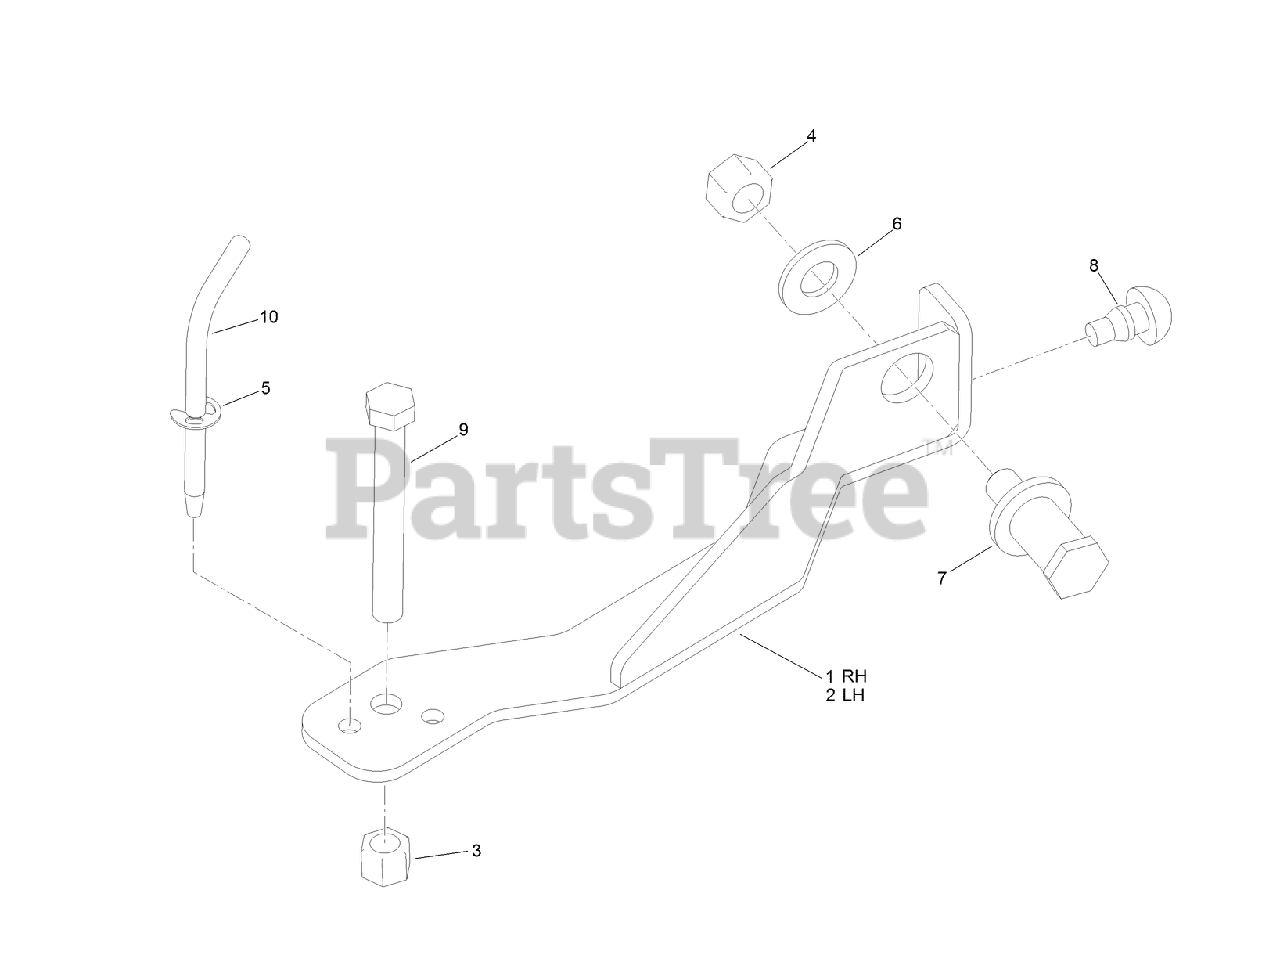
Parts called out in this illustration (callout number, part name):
1	HOLD-DOOR, RH
2	HOLD-DOOR, LH
5	RING-SNAP, EXTERNAL CRESCENT
6	WASHER-FLAT
7	STUD STRIKER ASM
8	BUMPER-RUBBER
9	BOLT-HHCS
10	PIN-DOOR, HOLD OPEN
